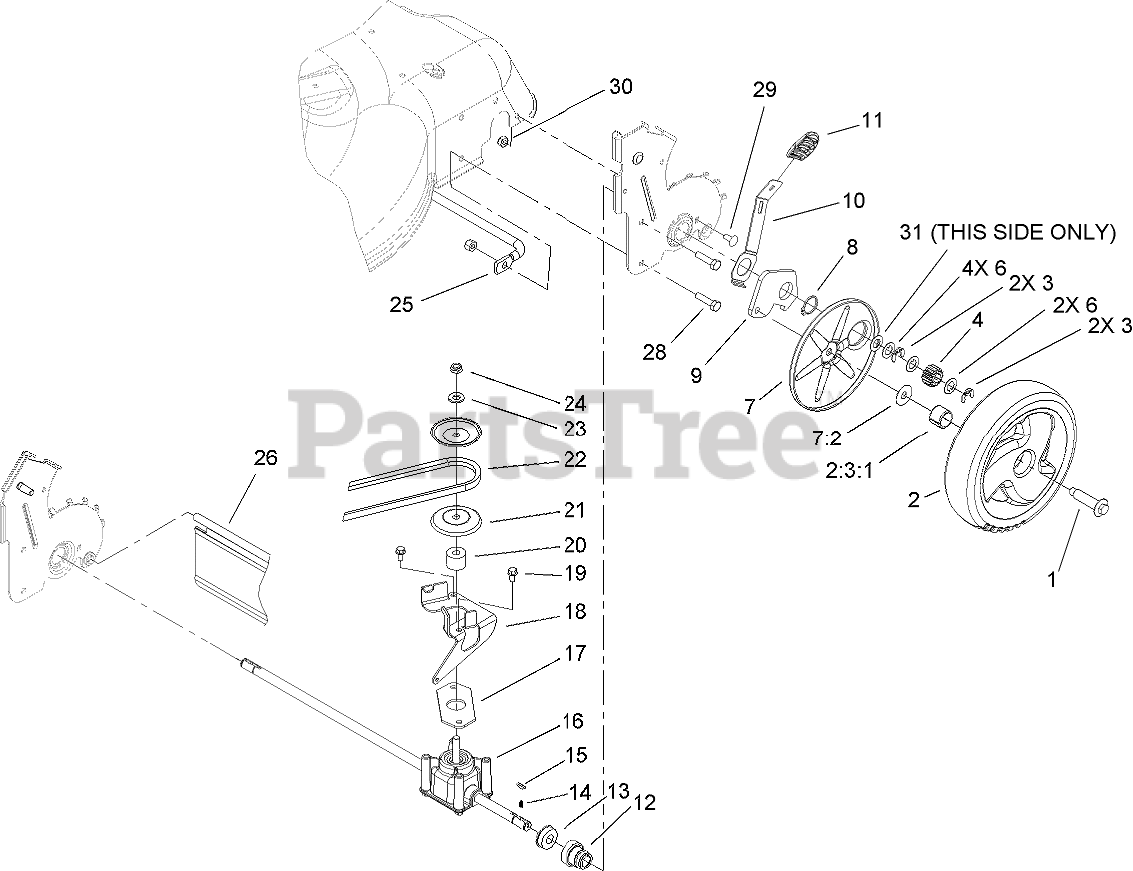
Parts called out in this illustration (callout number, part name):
1	BOLT-SHOULDER
2	Wheel Gear ASM
2:3	Wheel ASM
2:3:1	BUSHING
3	RING-CLIP, LOCKING
4	Gear-Pinion, 15t
6	Washer-Thrust
7	COVER-WHEEL
7:2	WASHER-STEPPED
8	RING-RETAINING
9	Arm-Pivot, Rear (LH)
10	Arm-Spring
11	Knob-Lever, HOC
12	RETAINER-BEARING, HOC
13	BEARING-BALL
14	SPRING-COMPRESSION
16	TRANSMISSION ASM
17	GASKET-GEARBOX
18	BRACKET-PIVOT
19	SCREW-HWH
20	SPACER
21	PULLEY-HALF
22	BELT-V
23	WASHER-FLAT
24	NUT-HEX
25	BRACE-PLATE, HOC
26	Shield-Trailing
28	SCREW-HH
29	SCREW-CARR
30	NUT-LOCK, NI
31	WASHER-PLAIN
